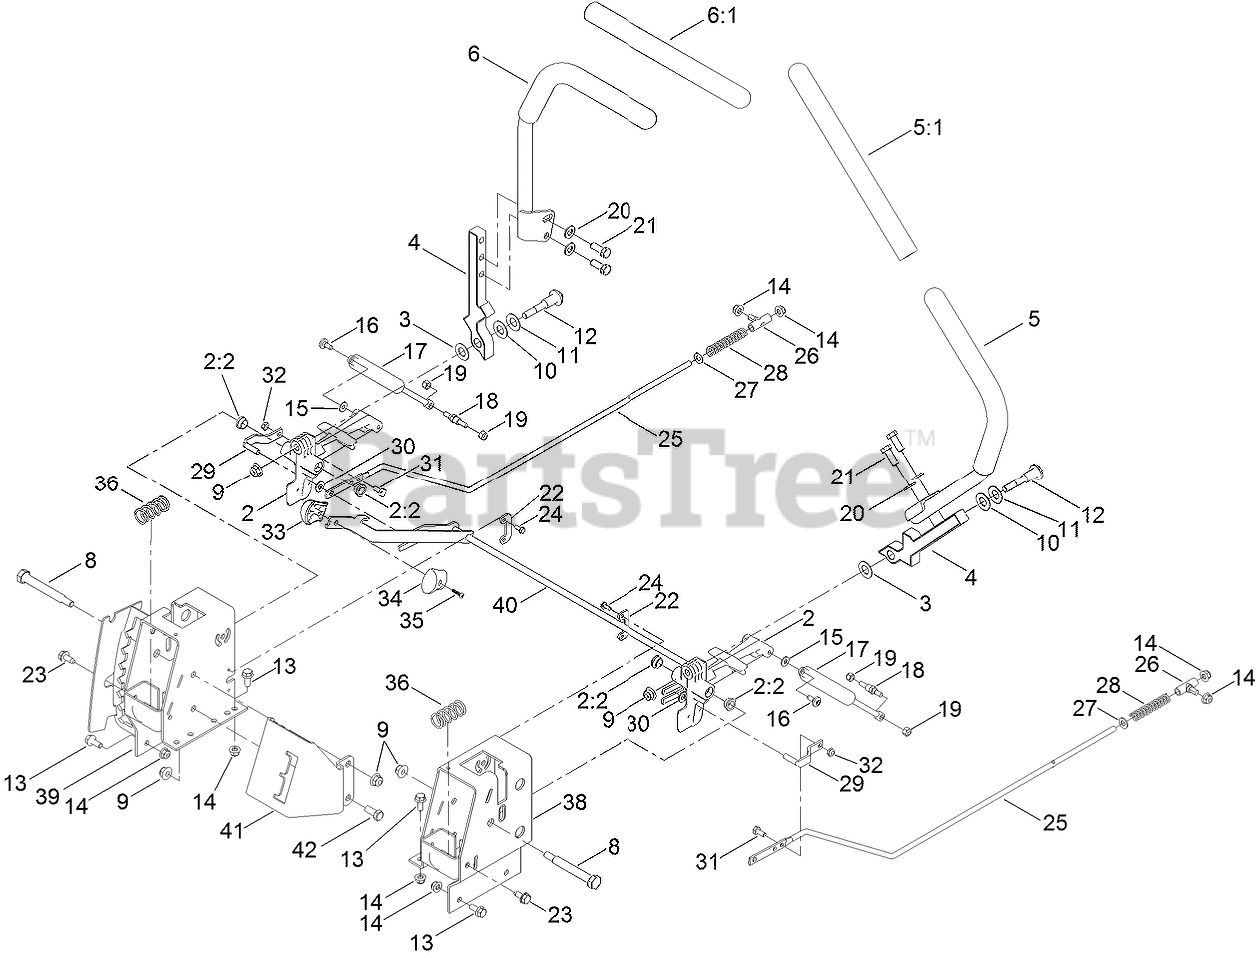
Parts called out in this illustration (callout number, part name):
2	ACTUATOR ARM ASM
2:2	BUSHING-FLANGE
3	WASHER-NYLON
4	ARM-CONTROL
5	HANDLE-CONTROL, LH
6	HANDLE-CONTROL, RH
8	BOLT-PIVOT
9	NUT-HF, NI
10	WASHER
11	WASHER-BELLEVILLE
12	BOLT-PIVOT
13	SCREW-HHF
14	NUT-HF, NI
15	WASHER
16	SCREW-SHOULDER
17	DAMPER
18	STUD-DAMPER
19	NUT-LOCK, NI
20	WASHER-FLAT
21	SCREW-HH
22	RETAINER
23	SCREW-HWHTF
24	SCREW-TAPTITE
25	ROD-HYDRO
26	MOUNT-ROD, HYDRO
27	WASHER-PLAIN
28	SPRING-RETURN, NEUTRAL
29	PIN-ROD, HYDRO
30	SPACER-NYLON
31	SCREW-HH
32	NUT-LOCK, NI
33	KNOB-RH
34	KNOB-LH
35	SCREW-PPH
36	SPRING-RETURN
38	BOX-CONTROL, LH
39	CONTROL BOX ASM
40	SPEED CONTROL ASM
41	GATE-CONTROL, SPEED
42	SCREW-HH
